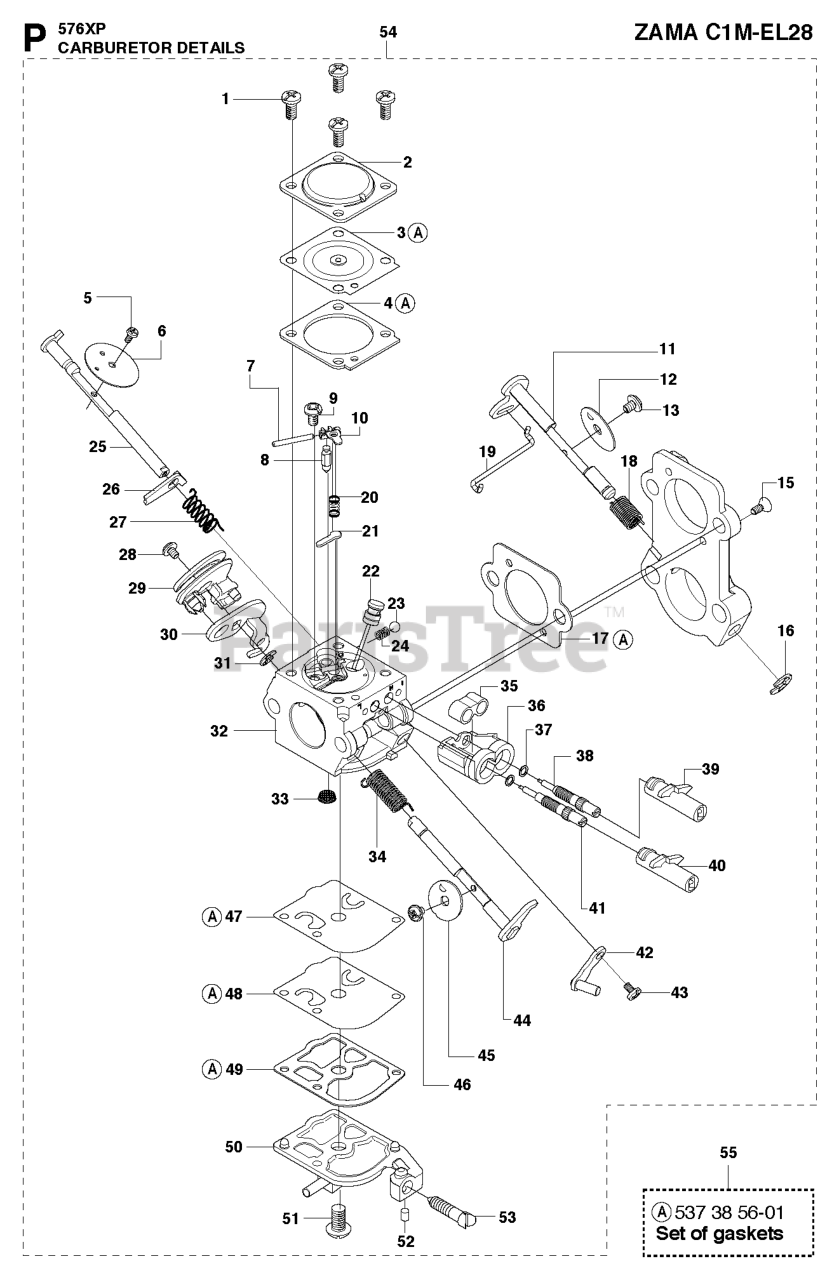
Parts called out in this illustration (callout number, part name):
1	SCREW
2	COVER
3	DIAPHRAGM
4	GASKET
5	SCREW
6	CHOKE FLAP
7	PIN RETAINING SCREW
8	INLET NEEDLE
9	SCREW
10	LEVER
11	SHAFT
12	THROTTLE FLAP
13	SCREW
15	SCREW
16	CLIP
17	GASKET
18	SPRING
19	ROD
20	SPRING
21	PLUG
22	JET
23	BALL
24	SPRING
25	CHOKE SHAFT
26	LEVER
27	SPRING
28	SCREW
29	LEVER
30	LEVER
31	CLIP
32	RP CARBURETOR
33	STRAINER
34	SPRING
35	SLEEVE
36	SLEEVE
37	WASHER
38	NEEDLE HIGH SPEED
39	LIMITER
40	LIMITER
41	LOW SPEED NEEDLE
42	LEVER
43	SCREW
44	THROTTLE SHAFT
45	FLAP
46	SCREW
47	PUMP DIAPHRAGM
48	DIAPHRAGM
49	GASKET
50	COVER
51	SCREW
52	PLUG
53	SCREW
54	RP CARBURETOR
55	GASKET SET
